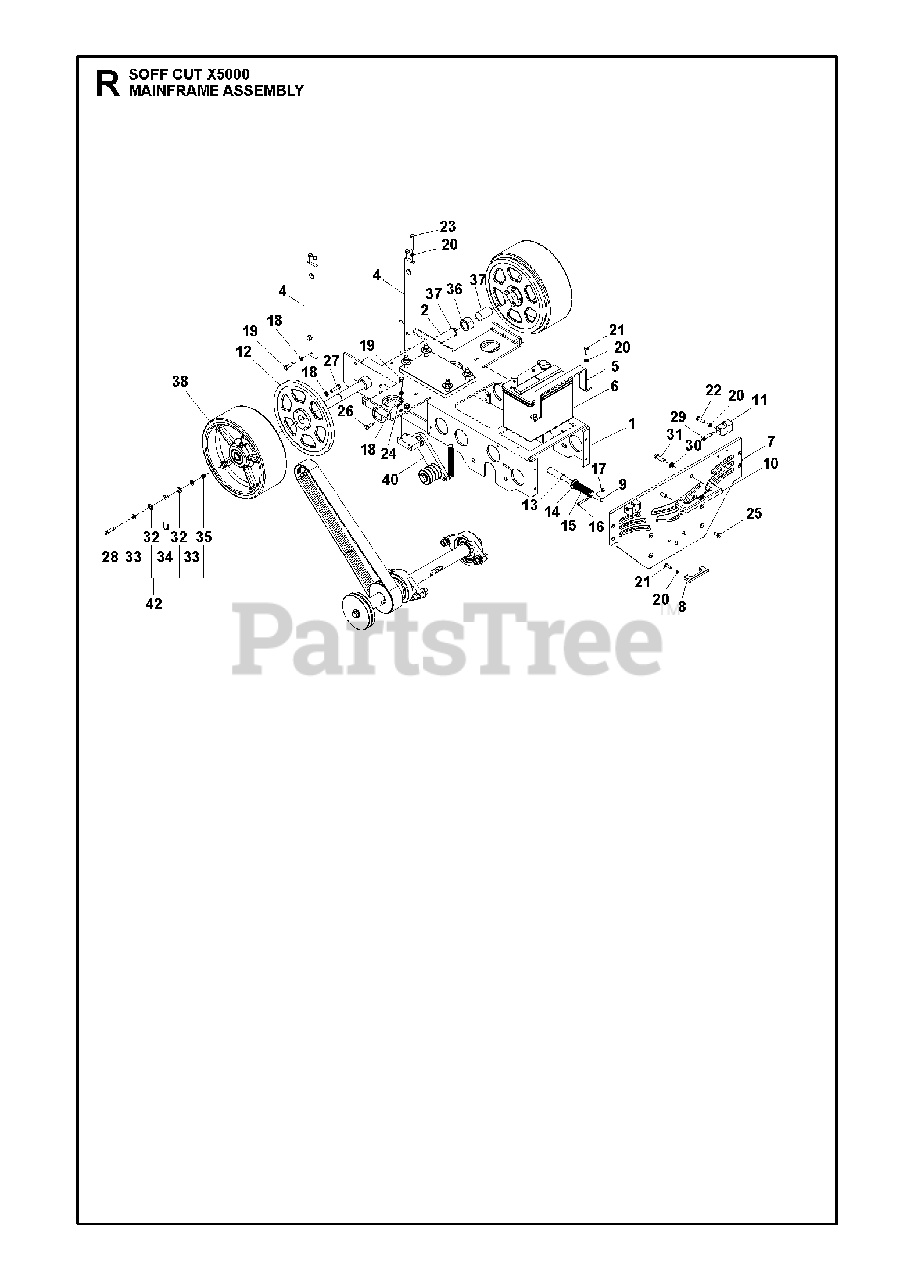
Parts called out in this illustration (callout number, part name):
1	MAINFRAME X5000 (SEND PRINT
3	ARM. CROSSBAR SUPPORT
12	ARBOR LOCK 3/4 X 2.35
23	WASHER
32	FLT WSH 5/16 I.D. TRA 512
